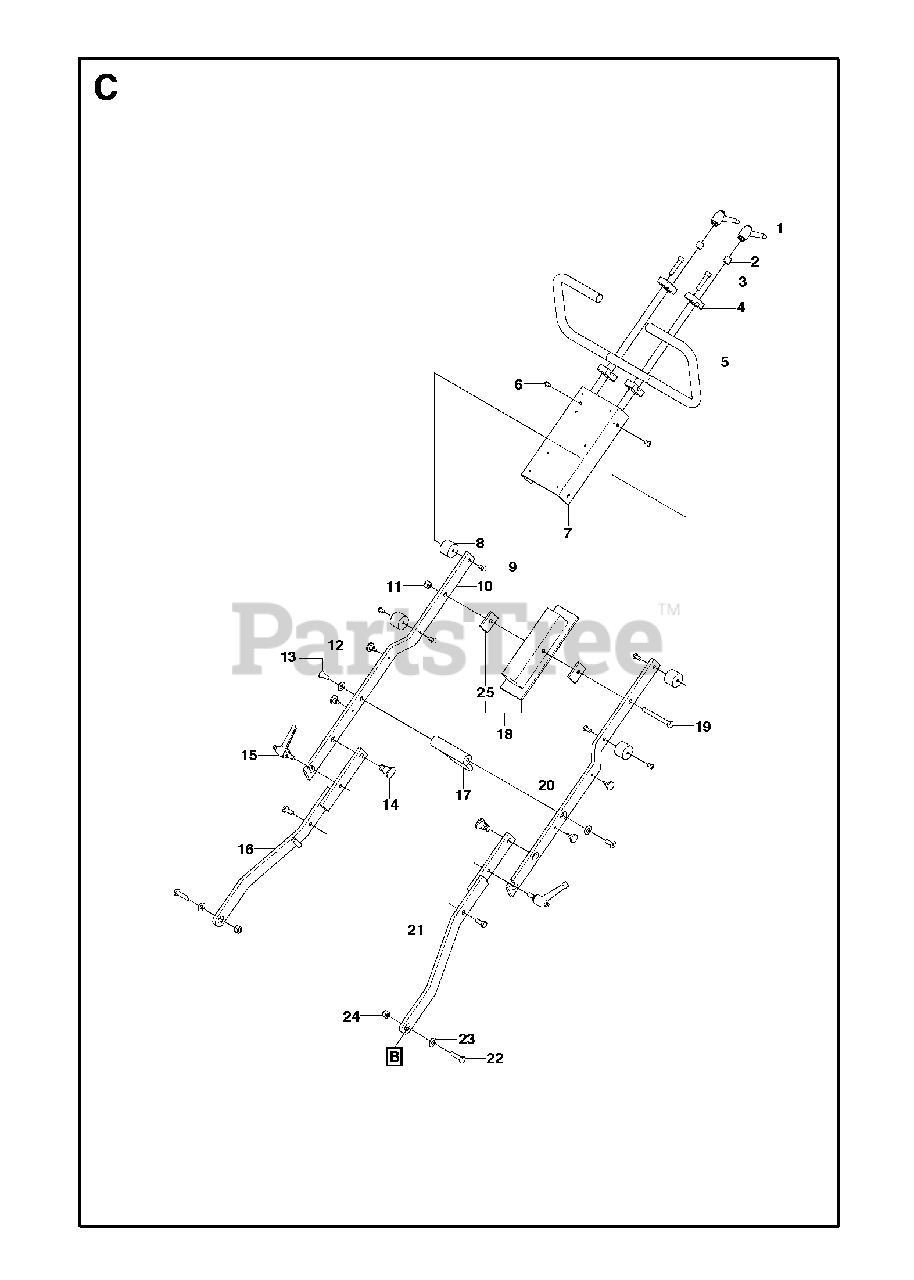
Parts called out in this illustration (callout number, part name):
9	SCREW EHHM
11	HEXAGON LOCKING NUT
23	WASHER
24	HEXAGON LOCKING NUT
